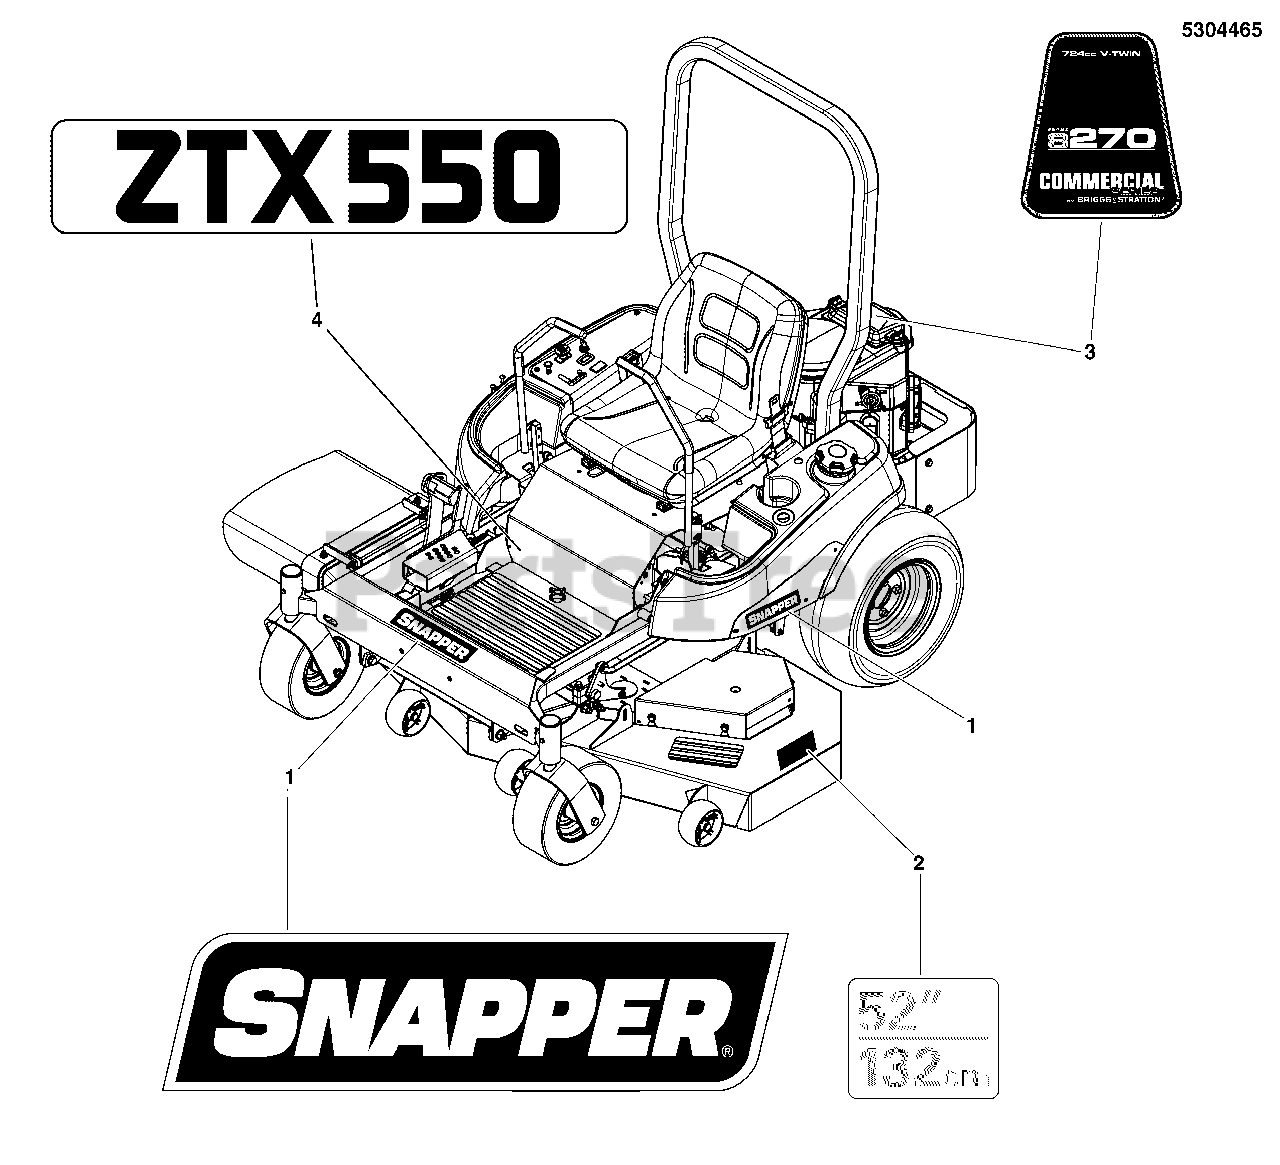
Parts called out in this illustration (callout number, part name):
1	DECAL, Logo, Snapper
2	DECAL, MOWER WIDTH 52IN/132CM
3	LABEL, POWER
4	DECAL, SNP, ZTX550
